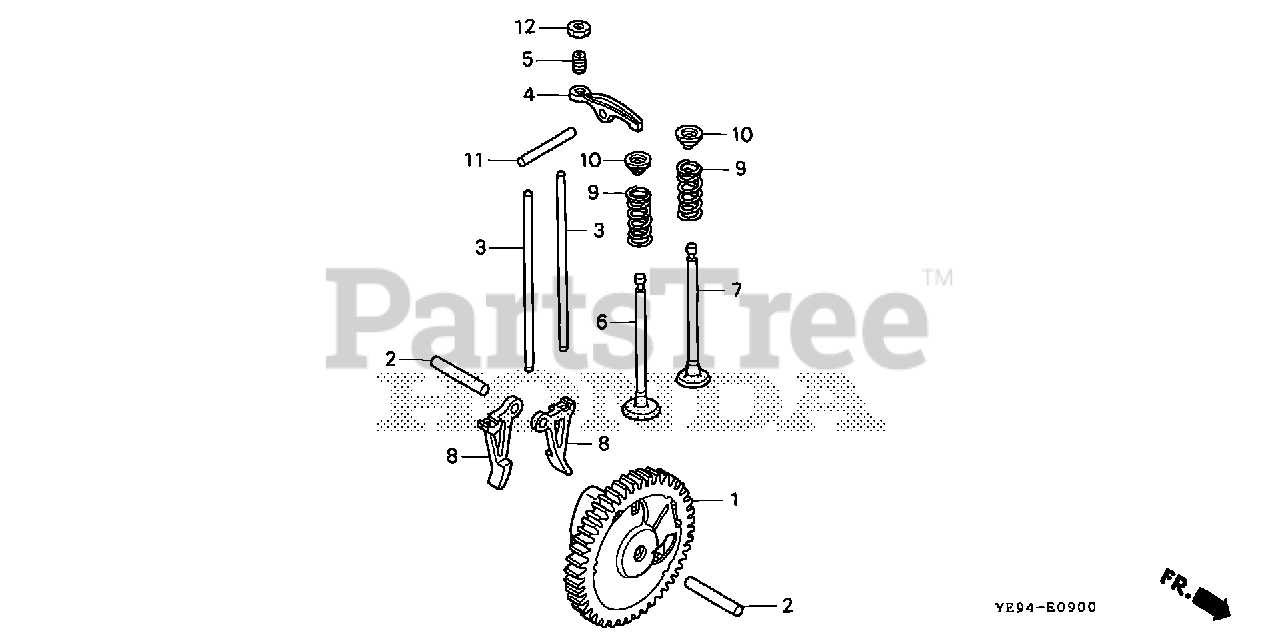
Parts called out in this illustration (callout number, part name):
1	CAMSHAFT ASSY.
2	ROLLER (5X23.8)
4	ARM, VALVE ROCKER
5	PIVOT, ROCKER ARM
6	VALVE, IN.
7	VALVE, EX.
8	LIFTER, VALVE
9	SPRING, VALVE
10	RETAINER, VALVE SPRING
11	ROLLER (4X28)
12	NUT, TAPPET ADJUSTING
